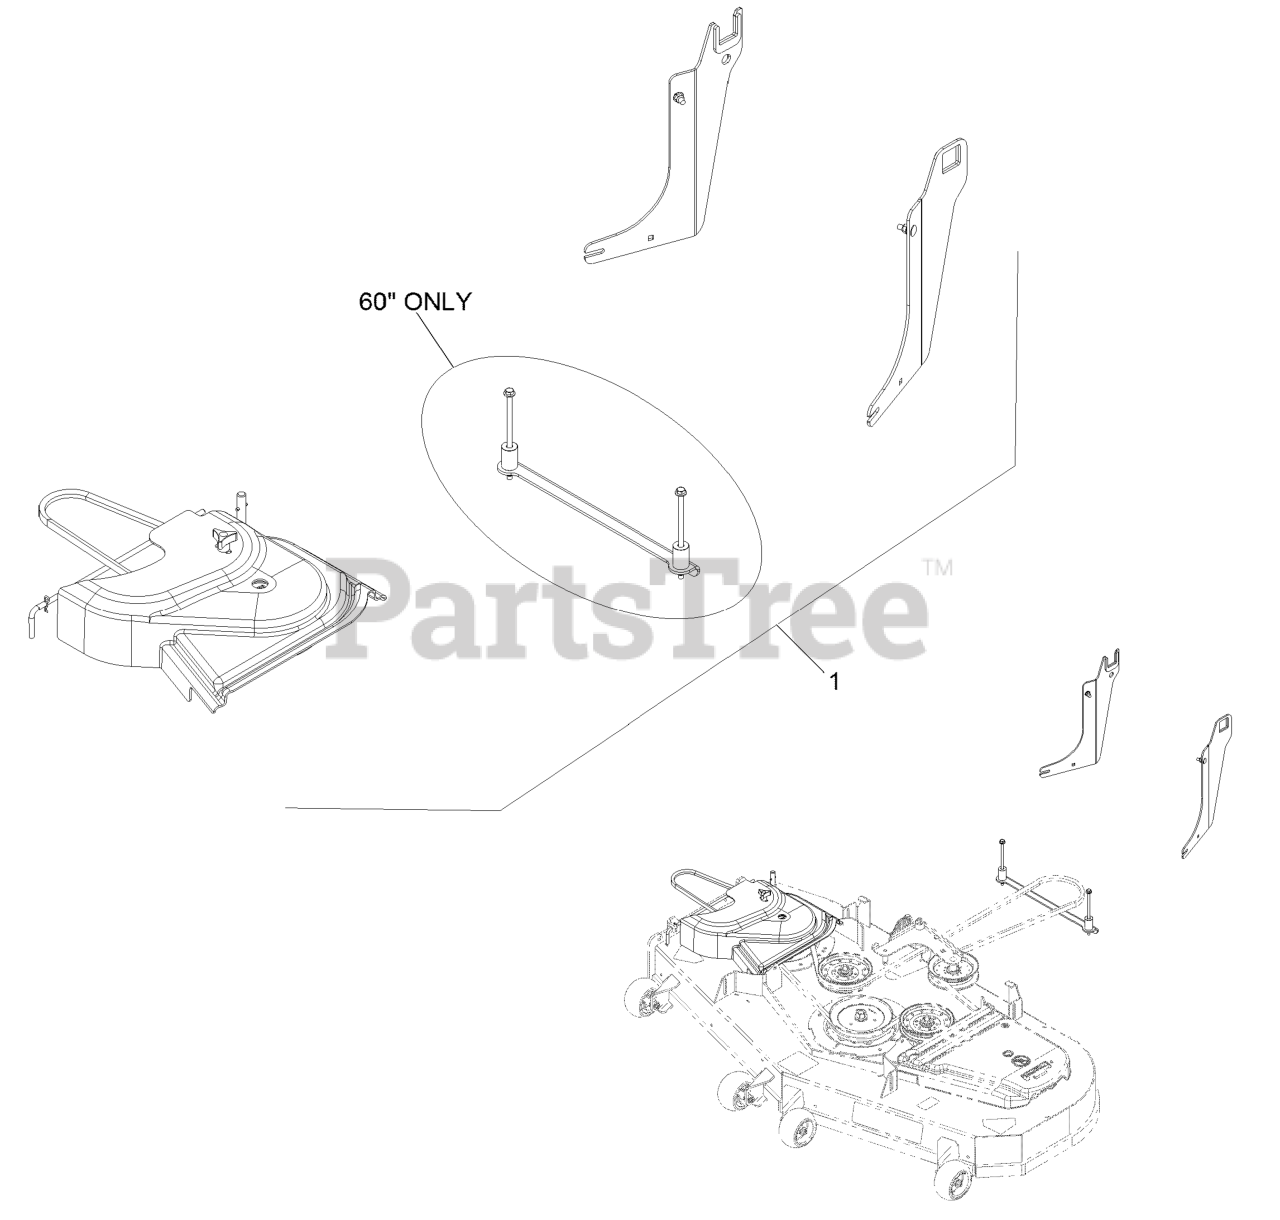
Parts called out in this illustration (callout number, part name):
1	Kit-Completing Qsp 44 Uve
1	Kit-Completing Qsp 48 Uve
1	Kit-Completing Qsp 52 Uve
1	Kit-Completing Pi 44 Uve
1	Kit-Completing Pi 48 Uve
1	Kit-Completing Pi 52 Uve
1	Kit-Completing Pn60 Uve
